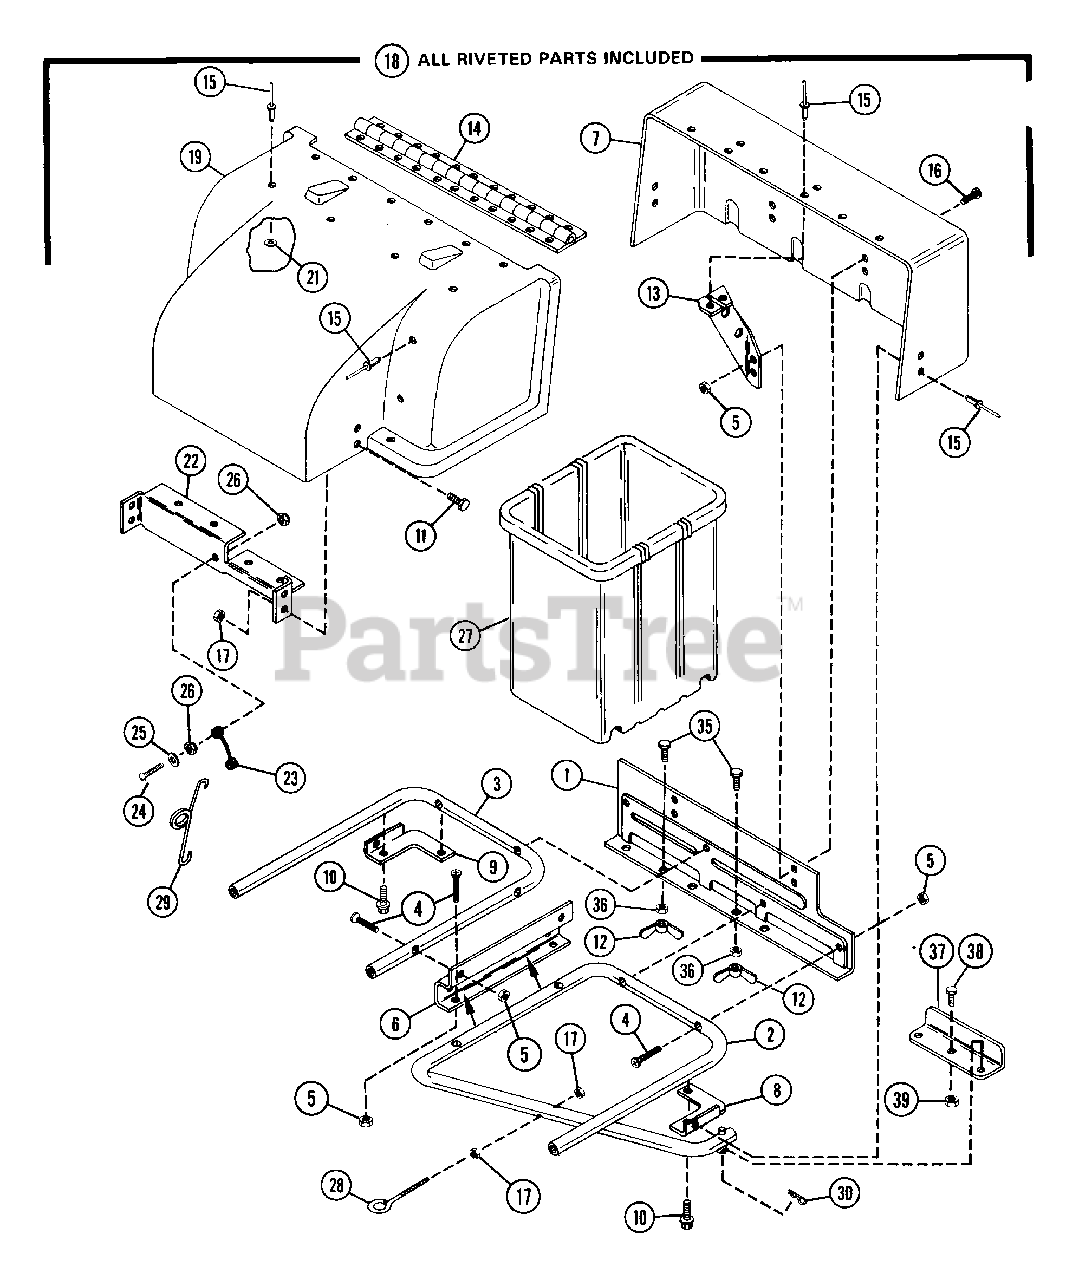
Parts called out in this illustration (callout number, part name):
1	MOUNTING BRACKET
2	RIGHT TUBE
3	CENTER TUBE
4	SCR-MCH .31-18X1.50 CROVCNTRS
5	NUT-LK .312-18 GR A PL
6	TUBE BRACKET
7	STATIONARY COVER
8	RH CORNER BRACKET
9	LH CORNER BRACKET
10	SCR-TAP .312-18X.50 HWH PL TR
11	BLT-HEX .25-20X.50 PL GR2
12	NUT-WING W/INSERT .312 - 18
15	RVT-POP .187X.402 DOME ST
16	SCR-MCH .31-18X.62 SLTR PL
17	NUT-LK-CTR .250-20 PL
18	COVER ASSEMBLY
19	COVER
21	WSHR-FL-STL .188X.438X.049 PL
22	COVER BRACKET
23	BATTERY STRAP
24	SCR-MCH 10-24X.88 SLRH PL
25	WSHR-FL-STL .194X.492X.047 PL
26	NUT-LK TOP 10-24 PL
27	GRASS BAGGER BASKET
28	EYEBOLT
29	HOOK
30	PIN-HAIR INT .08X.38X1.42 YWZC
31	SCR-MCH .31-18X1.25 SLTR PL
35	BLT-HEX .31-18X1.50 GR2 YWZC
36	NUT-HEX .312-18
37	BRACKET
38	BLT-HEX .50-13X1.00 PL GR2
39	NUT .50-13 PL
42	WSHR-LK .500X.151 HVY PL
43	NUT-WING W/INSERT .312 - 18
